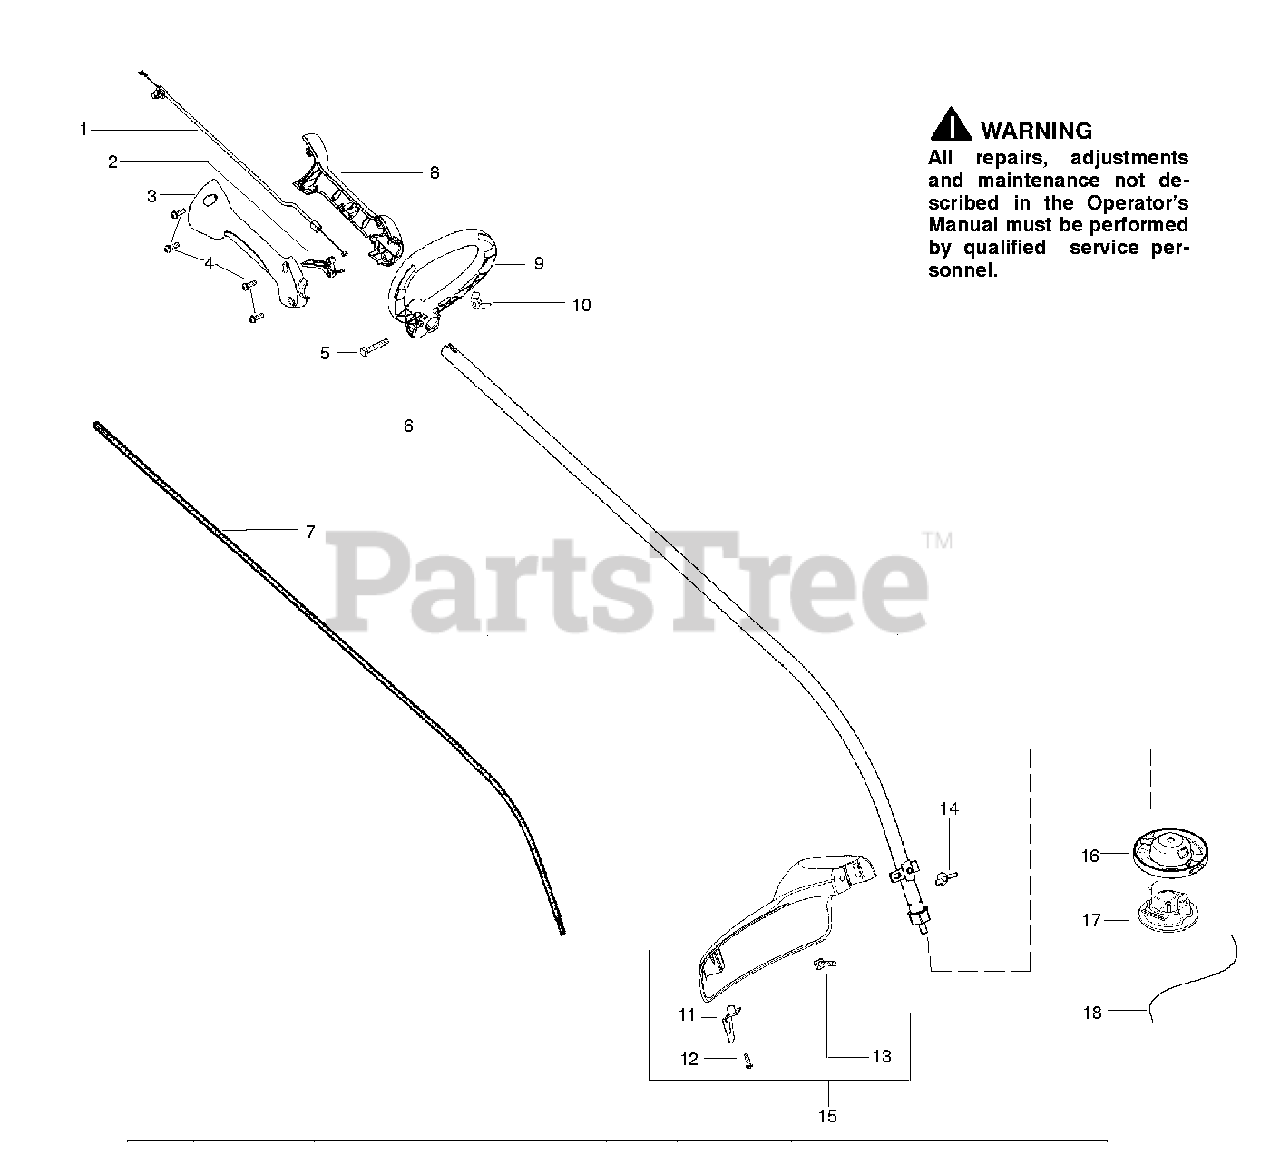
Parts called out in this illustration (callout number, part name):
1	ASSY THROTTLE CABLE
3	HSG THROTTLE RH
5	BOLT\-1/4-20X1-1/2
7	FLEXSHAFT CS 51"
8	HSG THROTTLE LH
9	ASSY ASSIST HANDLE
10	WINGNUT, TYPE 2
11	LINE CUTTER
12	SCREW - THROTTLE HOUSING
13	BOLT, TYPE 2
14	WINGNUT, TYPE 2
15	SHIELD KIT
16	HEAD CUTTING FIX LINE
17	CAP FIXED LINE 6
18	ACCY WE.095 X 16.5" LINE 12PCS
